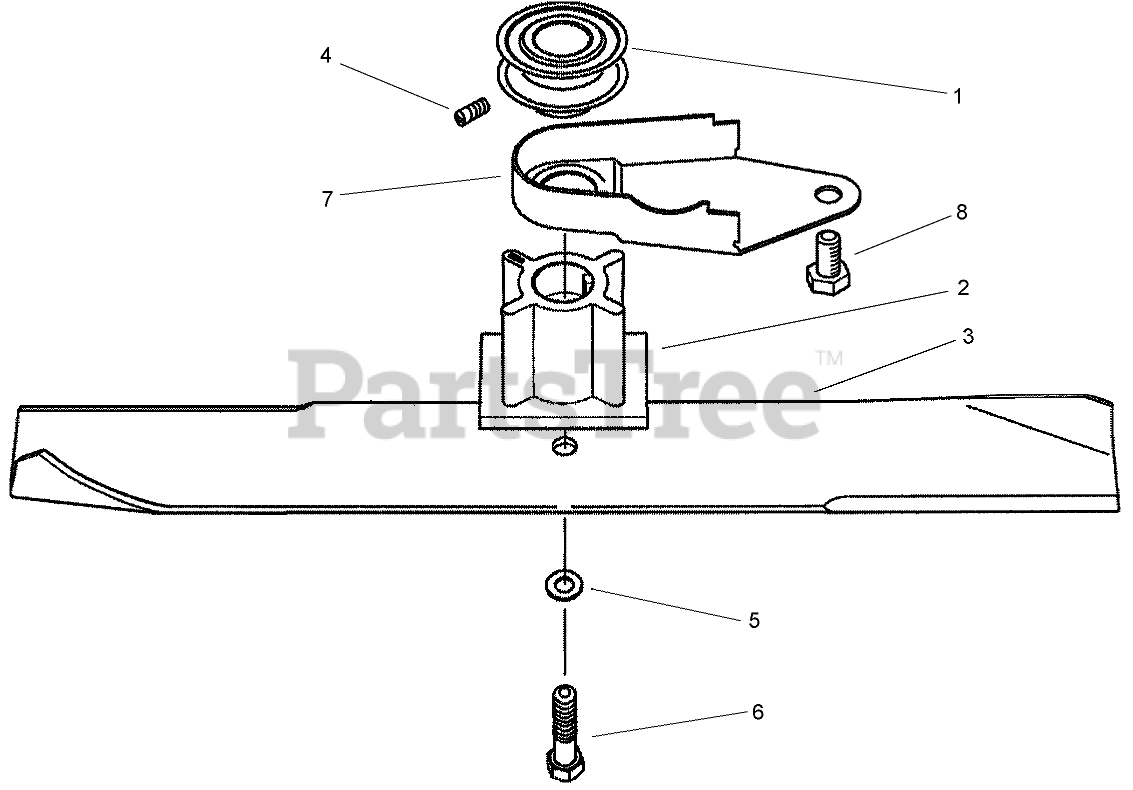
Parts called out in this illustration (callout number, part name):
1	RETAINER-BLADE
2	BLADE-RECYLER
3	WASHER-LOCK
4	BOLT-BLADE
5	Pulley-Driver
6	SCREW-WORM
7	COVER-GUIDE, BELT
8	SCREW-COVER, BELT
